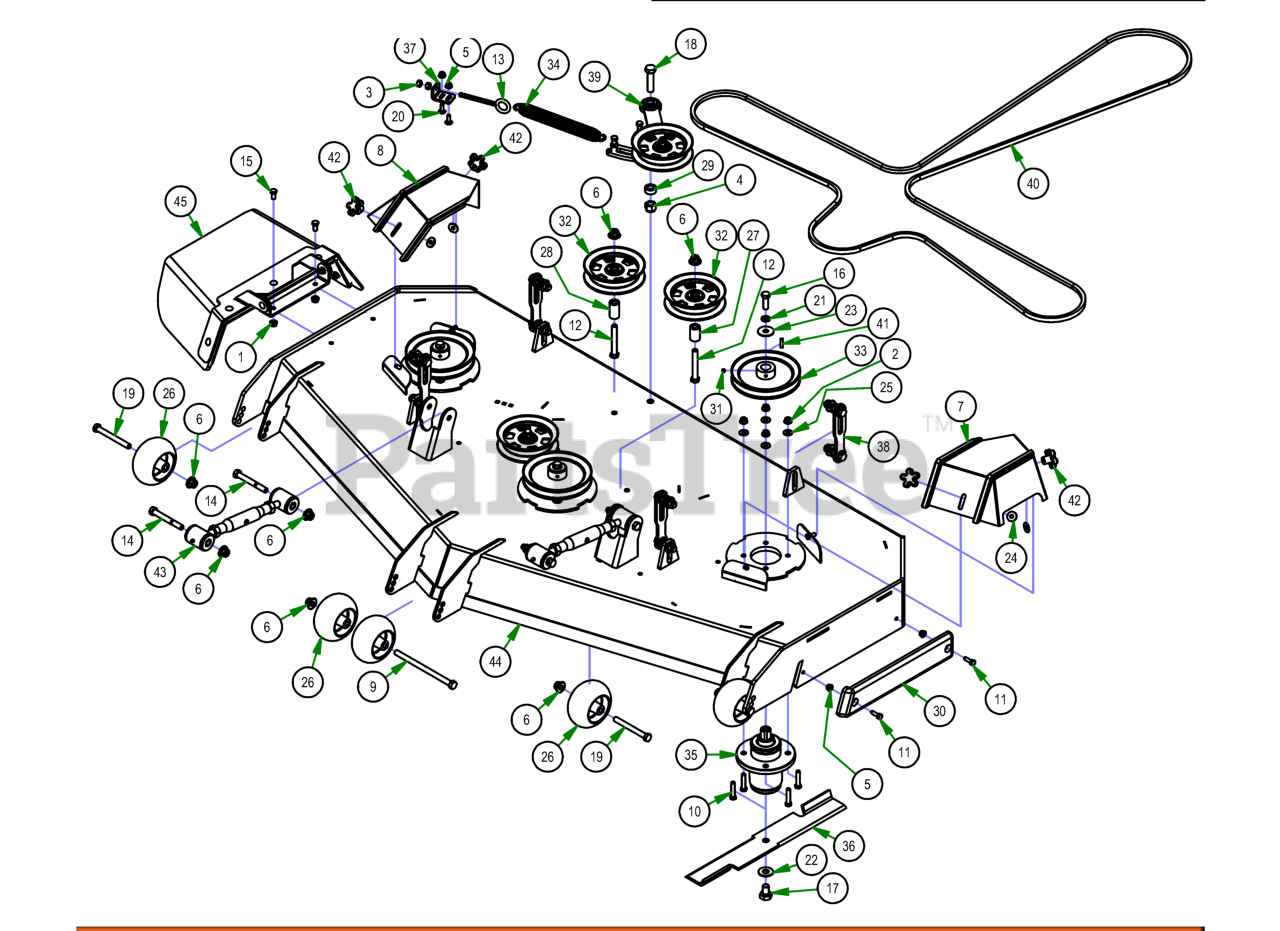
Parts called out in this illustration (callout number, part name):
1	3/8" Flange Nut
2	3/8-16 NYLON INSERT FLANGE LOCKNUT (GR.F) ZINC
3	3/8" Hex Nut
4	5/8 Std NC Nylock Nut
5	5/16" Nylon Flange Nut
6	1/2-13 NYLON INSERT FLANGE LOCKNUT ZINC
7	2019 72" Left Outlaw Gen2 Pulley Cover
8	2019 72" Right Outlaw Gen2 Pulley Cover
9	1/2-13 x 8 Hex Bolt Grade 5
10	3/8-16 X 1-3/4 HEX C/S (GR.5) ZC
11	5/16-18 x 1 GR 5 Hex Bolt Zinc
12	1/2 x 3 1/2 Flange Bolt Grade 8
13	4" 3/8-16 Eye Bolt
14	1/2" x 4" Bolt (Grade 8)
15	3/8" x 3/4" Hex Bolt
16	1/2"-20 x 1 1/2 - Grade 5 Fine Thread Bolt
17	5/8" x 1 1/2" Grade 8 Hex Bolt (Fine)
18	5/8" x 2 1/2" Grade 5 Hex Bolt (Coarse)
19	1/2" x 4 1/2" Bolt
20	5/16" x 7/8" Carriage Bolt
21	1/2" Lock Washer
22	5/8'' Flat Washer
23	1/2" Belleville Washer
24	.360 ID Plastic Washer-Black
25	5/16 USS FLAT WASHER (7/8 OD) ZINC
26	2019 Deck Wheel
27	.502 ID X .750 OD X 1.500 Long Spacer
28	1 3/4" Pulley Spacer
29	5/8" x 1/" Collar W/One Set Screw
30	REVISED TRIM BUMPER_20180226
31	5/16 Set Screw
32	5-3/4 Idler Pulley
33	7" Deck Pulley
34	2019 Outlaw Gen2 Deck Spring
35	OUTLAW SPINDLE ASSEMBLY
36	72" High Lift Fusion Blade
37	2019 Deck Eye Bolt Tab
38	Deck Hangar Assembly
39	2019 Renegade Deck Idler
40	Belt for 72" Renegade
41	1/4" x 1" Key
42	5/16" Knob
43	Turnbuckle
44	2019 Sloped 72" Deck
45	2019 Outlaw Gen2 Chute Assembly
